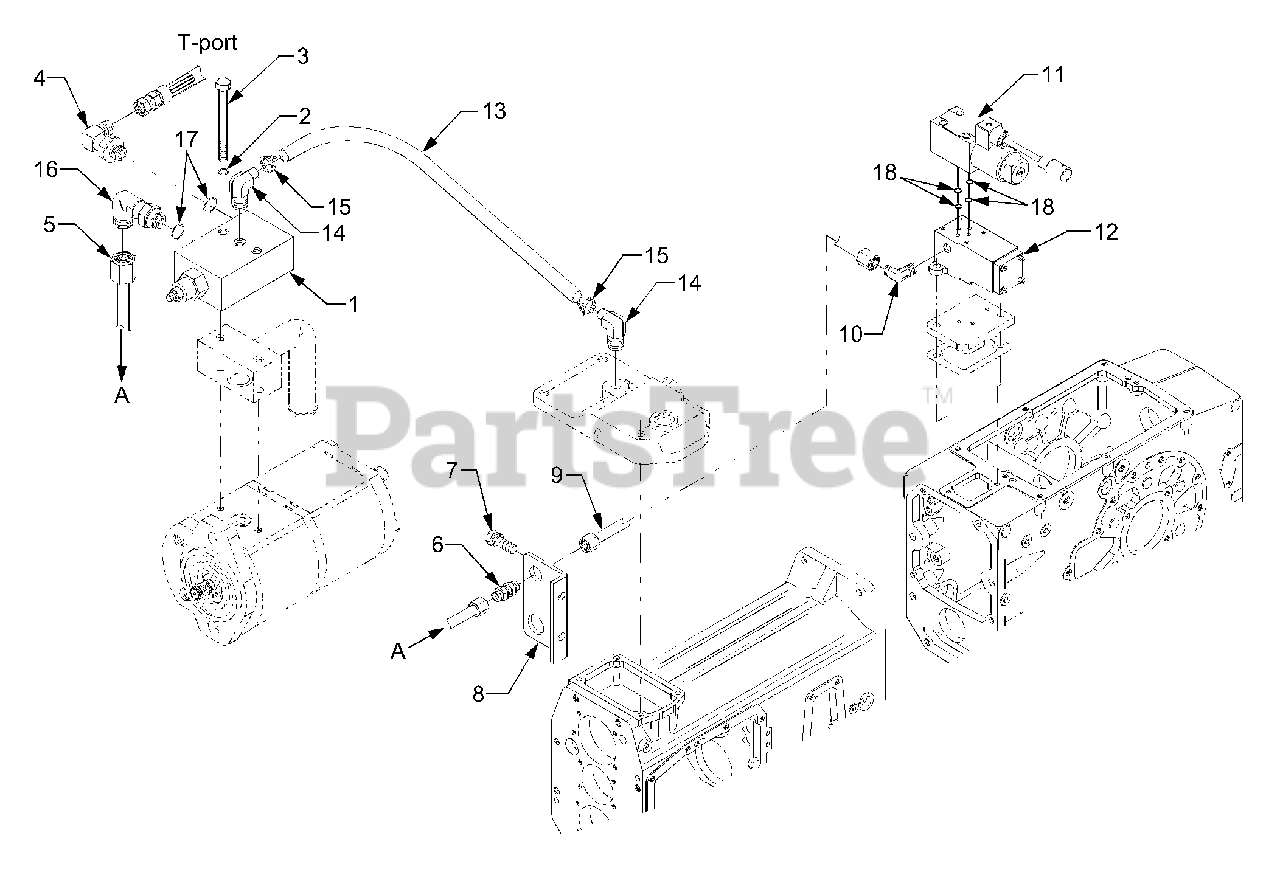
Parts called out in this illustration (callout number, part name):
1	Priority Valve Ass'y
2	Washer, Spring
5	Pipe 1, PTO Hydraulic
8	Bracket, Pipe
9	Pipe 2, PTO Hydraulic
11	Solenoid V/V Ass'y
12	Modulate V/V Ass'y
